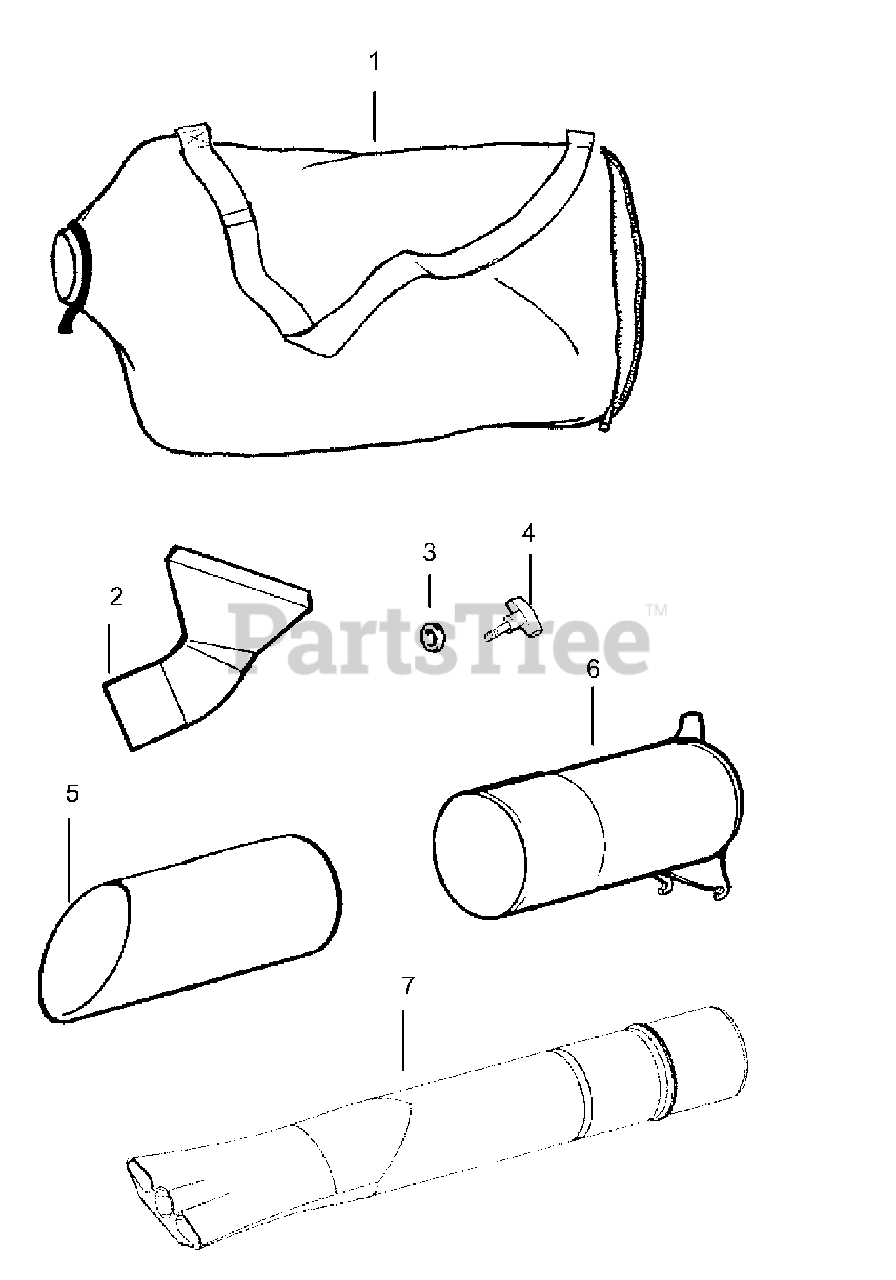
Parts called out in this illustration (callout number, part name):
1	Assy-Vac. Bag w/strap
2	Tube-Elbow Vac
3	Retainer-Vac Tube Knob
5	Tube-Lower Vac
6	Tube-Upper Vac
7	Tube-Blower
